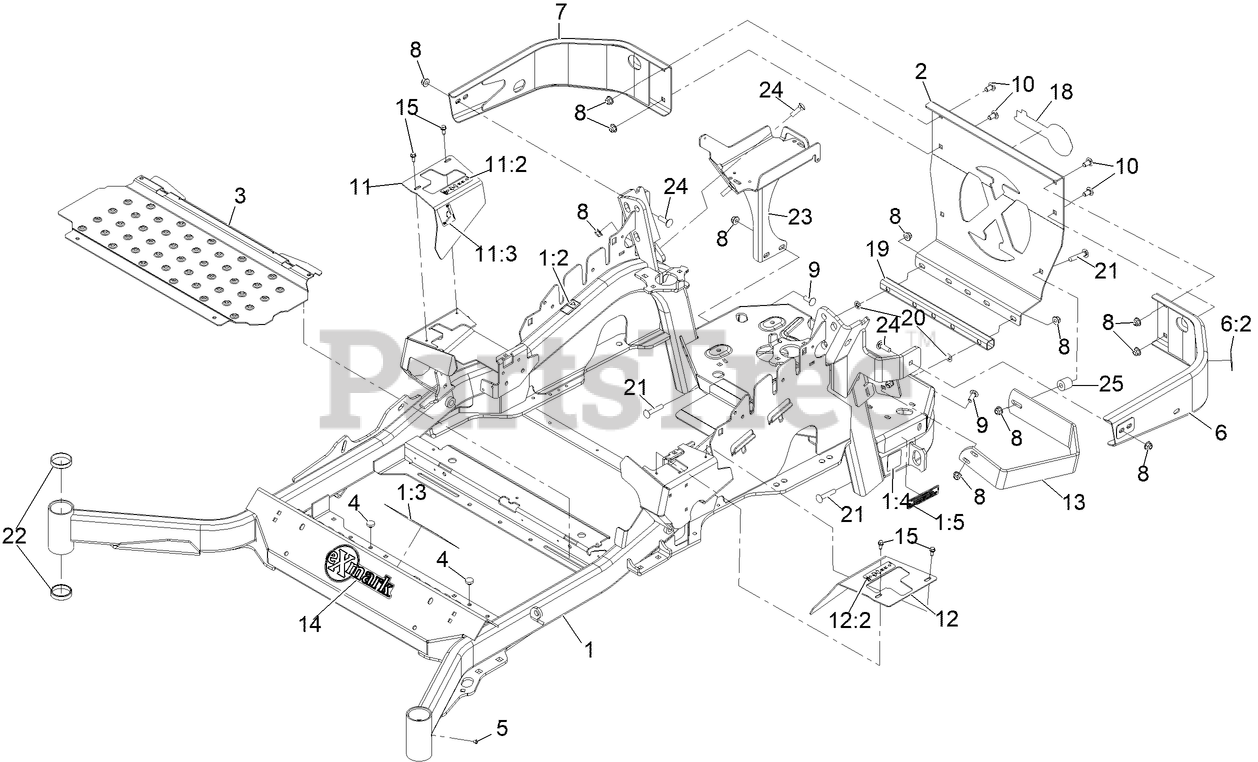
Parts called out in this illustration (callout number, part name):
1	MAINFRAME SERVICE ASM - 72
1:2	DECAL-WARNING
1:3	DECAL-DANGER
1:4	DECAL-HAZARD, PINCHED FINGER
1:5	DECAL-ARRESTOR, SPARK
2	PLATE,REAR GUARD
6	ASM-BUMPER REAR LH W/DECAL
6:2	DECAL-WARNING
7	WELD-BUMPER RH DBL HOLE
8	NUT-HF, NI
9	SCREW-CARR
10	SCREW-CARR
11	RH MOTION CONTROL COVER ASM
11:2	DECAL-CONTROL, MOTION
11:3	DECAL-PARK BRAKE, CE
12	LH MOTION CONTROL COVER ASM
12:2	DECAL-CONTROL, MOTION
13	GUARD-MUFFLER
14	DECAL-EXMARK
15	SCREW-HWH
18	DECAL, EXMARK LOGO
19	Spacer-Rear Guard Lower
20	NUT-PUSH
21	BOLT-CARRIAGE
22	CUP-BEARING
23	BATTERY MOUNT ASM
24	BOLT-CARR
